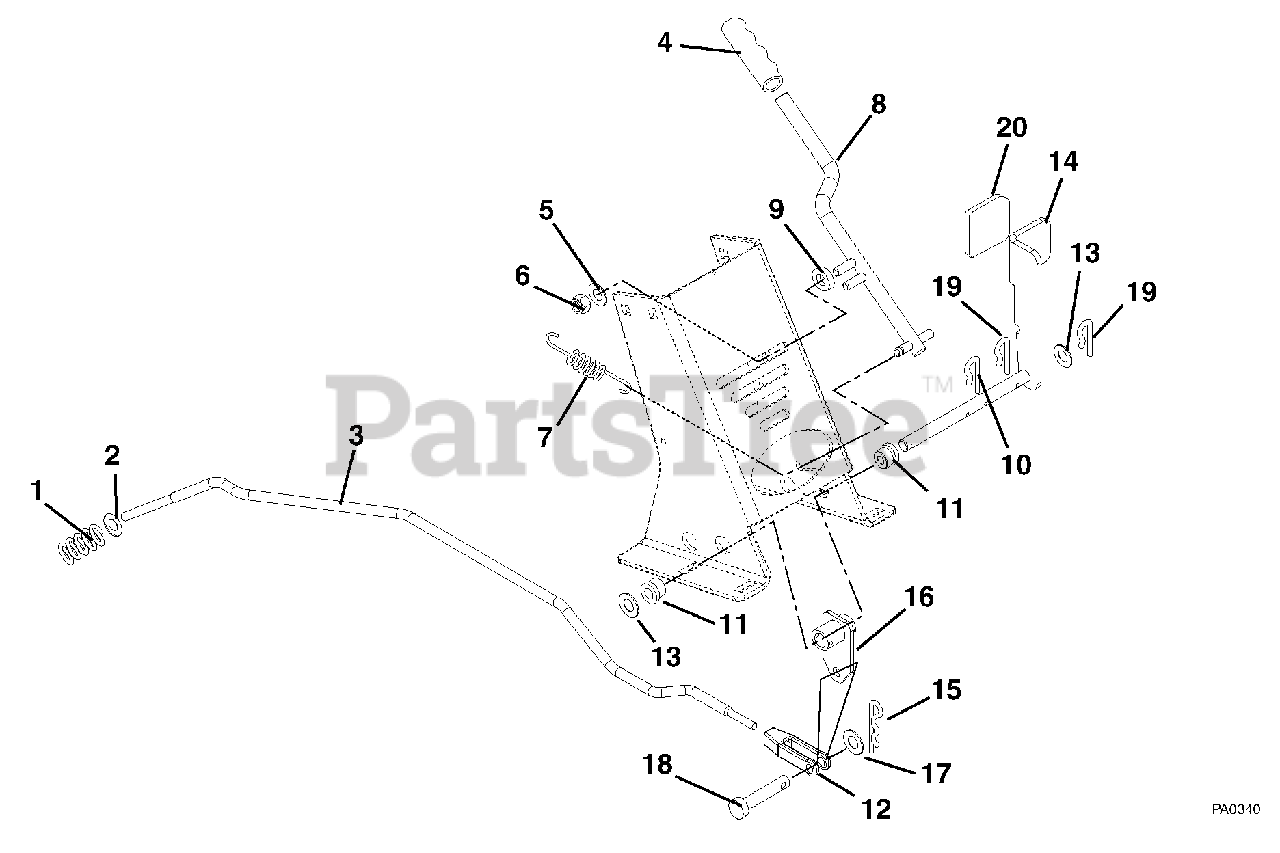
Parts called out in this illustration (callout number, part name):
1	Spring, Compression .080 x .52 x 2.90
2	Washer, Flat Steel .38 x .87 x .179
3	Rod, Brake
5	Washer, Flat Steel .38 x .875 x .083
6	Nut, Locking Top Flange .38-16
7	Spring, Tension .048 x .44 x 2.12
8	Weldment, Parking Brake
9	Bushing, Flange .406 x .88 x .27 x .140 Grade 2
10	Pin, Spring Clip
11	Bushing, Flange .515 x .75 x .745 x 1.00 Nylon
12	Yoke, .312-24 x 2.25
13	Washer, Flat Steel .505 x 1.00 x .062
14	Weldment, Brake Pedal
15	Pin, Hair
16	Brake Rod Arm and Hub
17	Washer, Flat Steel .38 x .87 x .179
18	Pin, Clevis .312 x .822
19	Clip, Spring
20	Grip, Pedal
